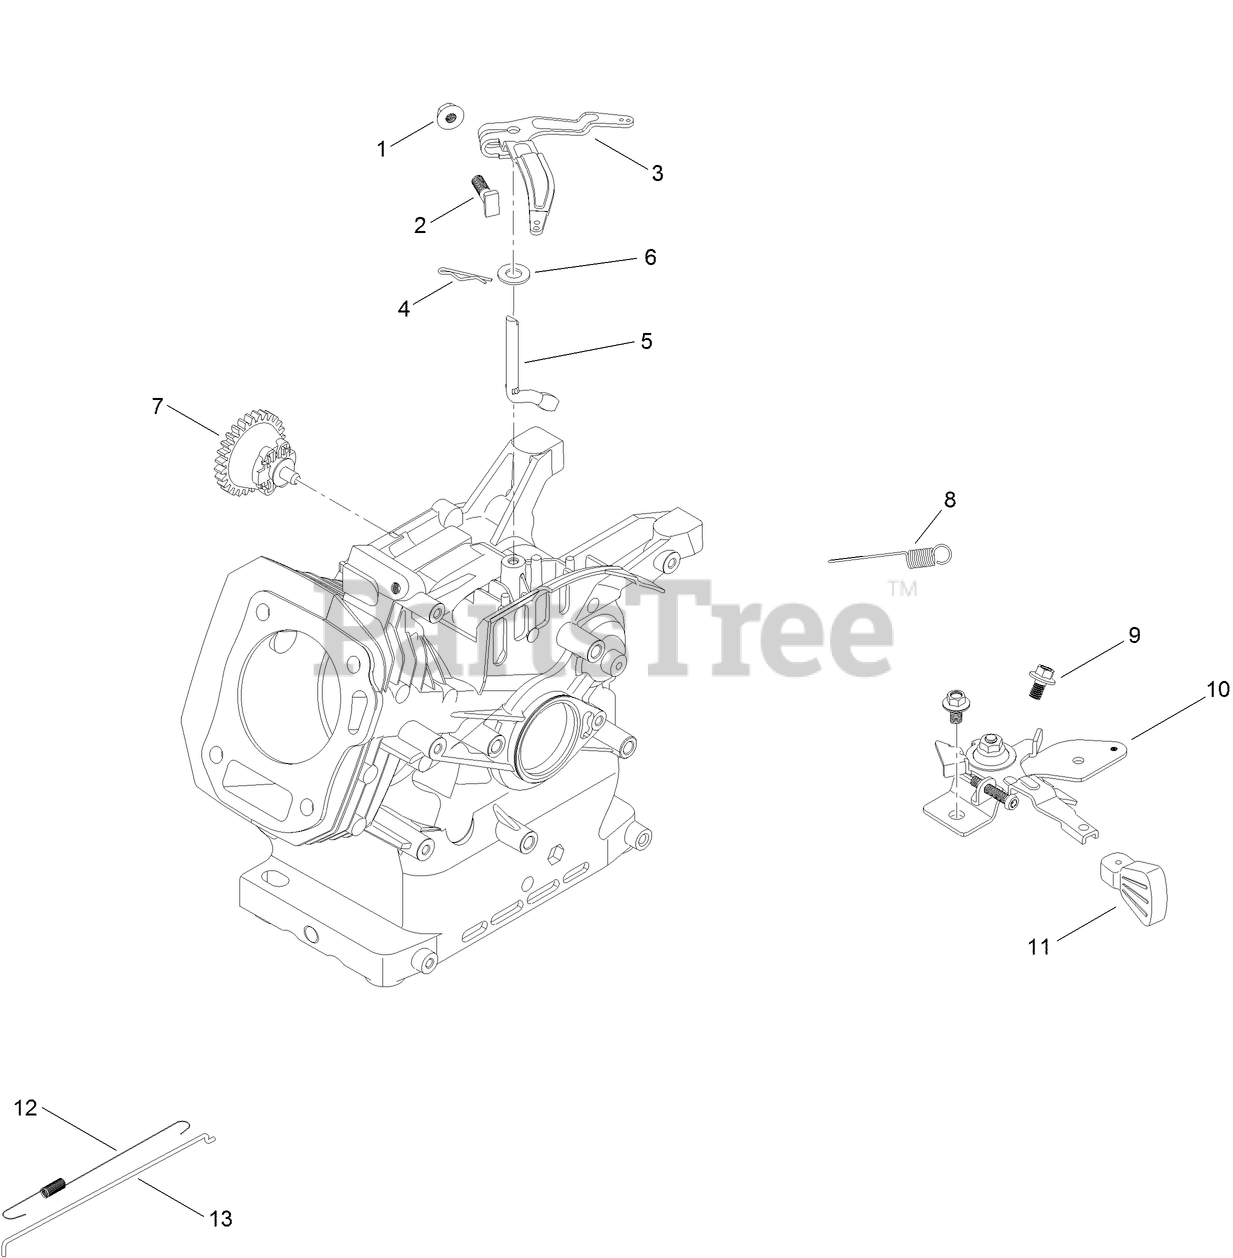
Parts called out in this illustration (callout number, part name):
1	NUT-FLANGE
2	BOLT-ARM, GOVERNOR
3	ARM-GOVERNOR
4	PIN-HAIR
5	SHAFT-GOVERNOR
6	WASHER-PLAIN
7	GOVERNOR GEAR ASM
8	SPRING-GOVERNOR
9	SCREW-HHF
10	SPEED CONTROL ASM
11	KNOB-CONTROL, THROTTLE
12	SPRING-RETURN, THROTTLE
13	ROD-GOVERNOR
